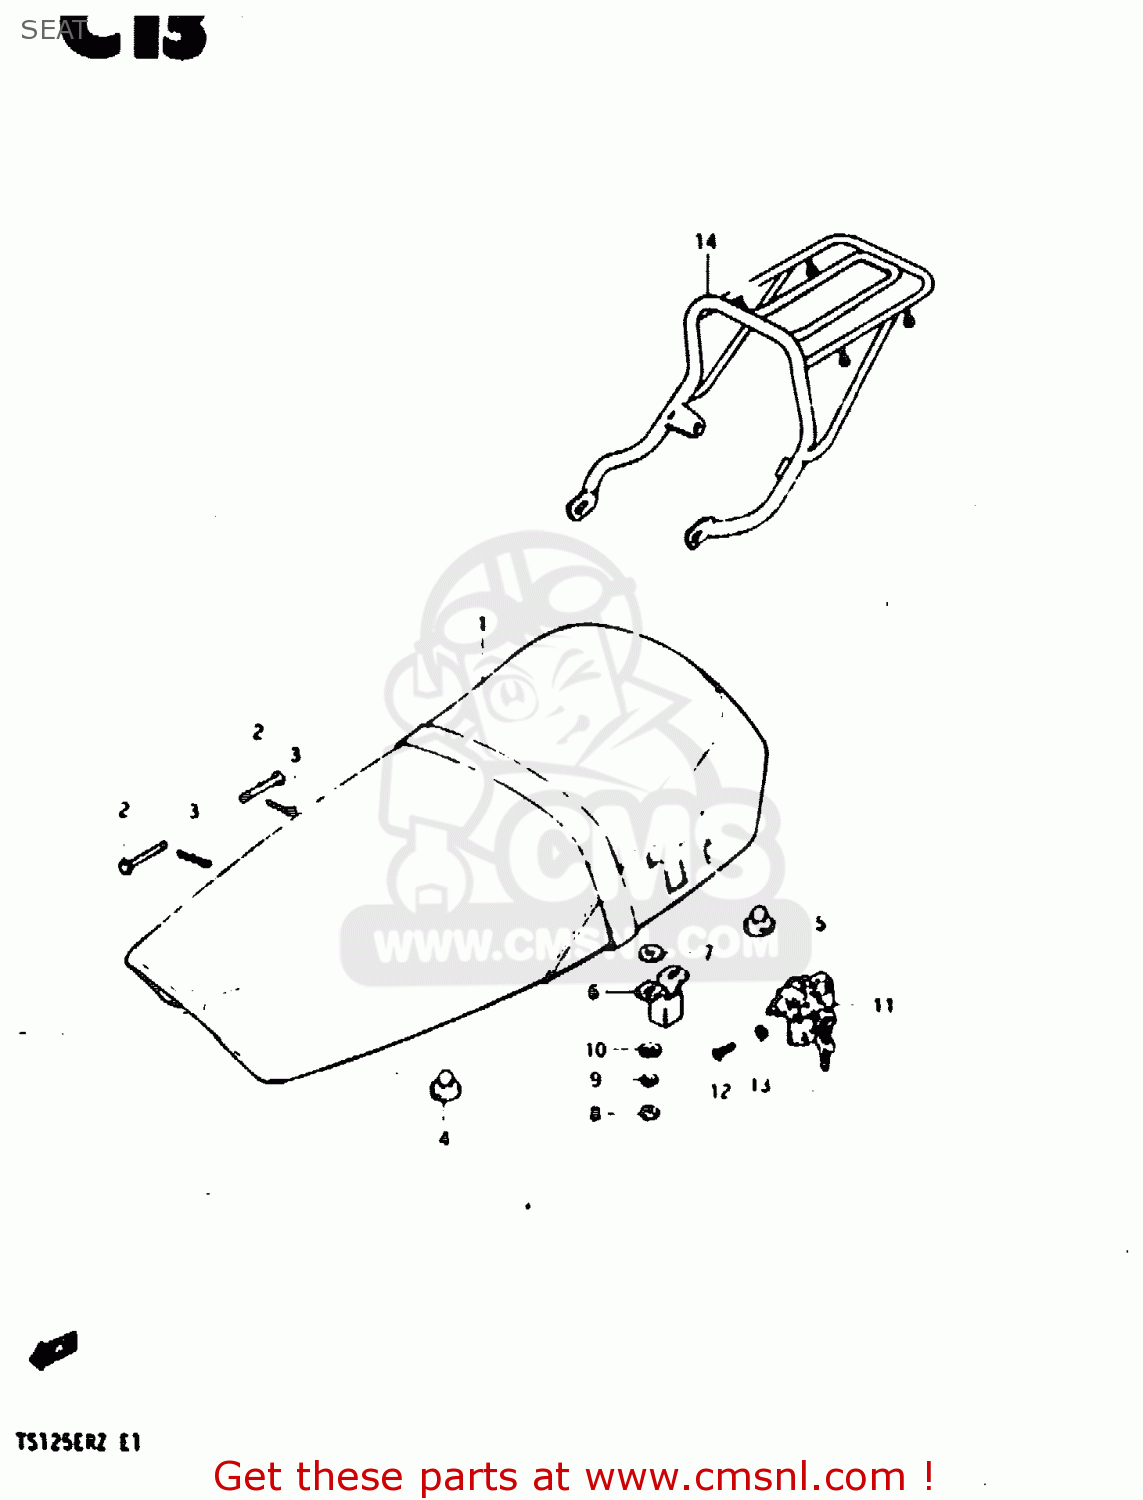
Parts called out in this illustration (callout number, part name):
1	SEAT ASSY (BLACK)
2	PIN
3	PIN
4	CUSHION
5	CUSHION
6	PLATE,CLAMP GUIDE
7	WASHER(8.5X18X1)
8	NUT
9	LOCK WASHER
10	WASHER
11	LOCK ASSY,SEAT
12	SCREW
13	LOCK WASHER
14	CARRIER, SPORTS
